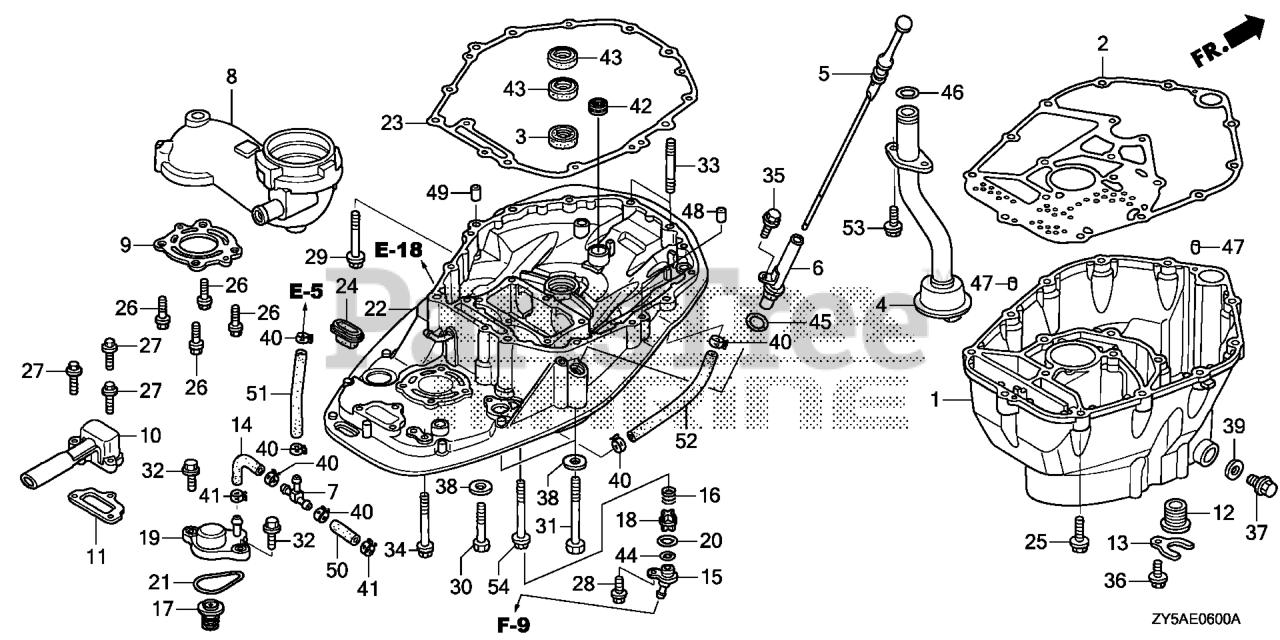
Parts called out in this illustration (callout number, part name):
1	CASE, OIL *TGRAY* (GRAY)
2	GASKET, OIL PAN
3	RUBBER, OIL PUMP
4	STRAINER, OIL
5	DIPSTICK, OIL
6	PIPE, OIL LEVEL
8	GUIDE, EX. *NH8* (DARK GRAY)
9	GASKET, EX. GUIDE
10	PORT, IDLE EX.
11	GASKET, IDLE EX. PORT
12	GROMMET, WATER TUBE
13	PLATE, WATER TUBE
14	TUBE, WATER RELIEF
15	COVER, FLUSH VALVE
16	SPRING, FLUSH VALVE
17	VALVE ASSY., RELIEF
18	VALVE, FLUSH
19	COVER, RELIEF VALVE
20	GASKET, FLUSH VALVE
21	O-RING, THERMOSTAT COVER
22	CASE, MOUNT *NH8* (DARK GRAY)
23	GASKET, MOUNT CASE
24	RUBBER, MOUNT CASE SEAL
25	BOLT, FLANGE (10X40)
26	BOLT, FLANGE (8X30)
27	BOLT, FLANGE (6X25)
28	BOLT, FLANGE (6X16)
28	BOLT, FLANGE (6X20) (ENGINE NO.)
29	BOLT, FLANGE (10X80)
30	BOLT, HEX. (12X70)
31	BOLT, HEX. (12X130)
32	BOLT, FLANGE (6X22)
33	BOLT, STUD (10X55)
34	BOLT, FLANGE (8X100)
35	BOLT, FLANGE (6X12)
36	BOLT, FLANGE (6X12) Use from Frame SN 1005249.
37	BOLT, DRAIN PLUG
38	WASHER, PLAIN (12MM)
39	WASHER, DRAIN PLUG (12MM)
40	CLAMP, TUBE (D10.5) (ENGINE NO.)
41	CLAMP, TUBE (D10.5) (ENGINE NO.)
42	BEARING, NEEDLE (20X28X13) (SOLID)
43	SEAL, WATER (22X35X7)
44	O-RING (16MM)
45	O-RING (11.5X3.5)
46	O-RING (20.6X2.6)
47	PIN A, DOWEL (6X10)
48	PIN A, DOWEL (10X16)
49	PIN A, DOWEL (14X20)
50	BULK HOSE, VACUUM (7X3000) (7X550)
51	BULK HOSE, VACUUM (7X3000) (7X550)
52	BULK HOSE, VACUUM (7X3000) (7X550)
53	BOLT, FLANGE (6X18)
54	BOLT, FLANGE (10X110)
